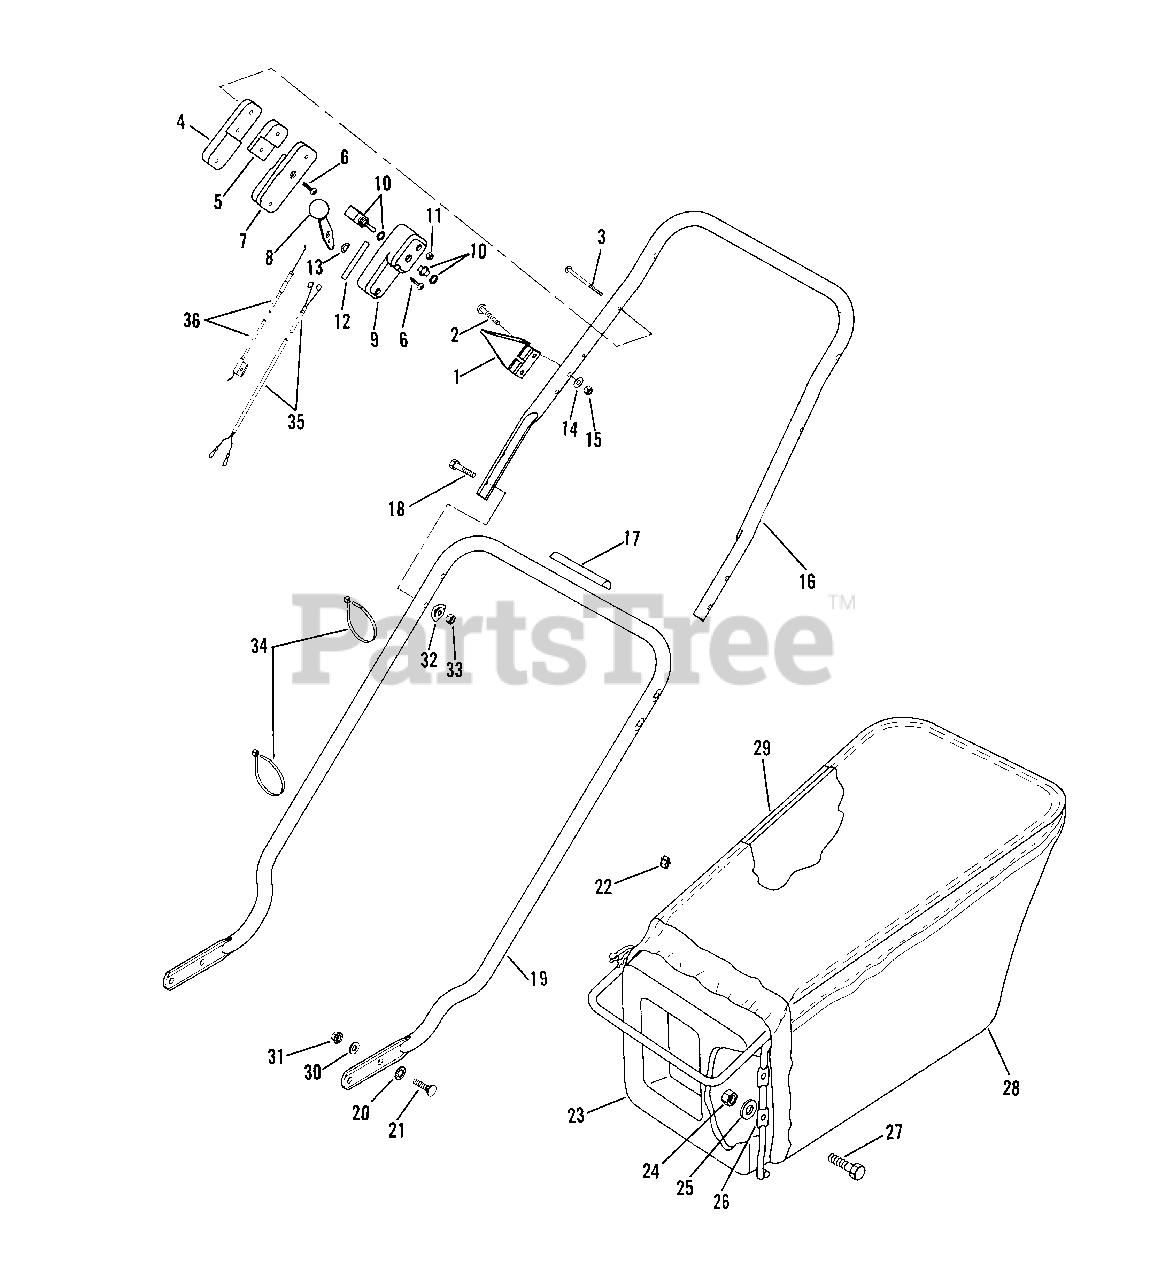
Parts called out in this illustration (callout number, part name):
1	Rope Guide Assembly
2	Screw-Rope Guide
3	Screw-Case to Handle
4	Control Case-Outer
5	Escutcheon Plate
6	Screw
7	Throttle Case-Center
8	Lever and Knob Assembly
9	Throttle Case-Inner
10	Switch Assembly
11	Nut
12	Decal-ON-OFF
13	Washer
14	Nut-Rope Guide
15	Washer
16	Handle-Upper
17	Decal-Special Training
18	Screw
19	Handle-Lower
20	Lockwasher
21	Bolt-Carriage
22	"S" Clip
23	Adapter
24	Nut
25	Washer
26	Latch Bar Assembly
27	Screw
28	Grass Bag
29	Hanger-Bag
30	Washer
31	Nut-Flanged
32	Washer-Curved
33	Nut
34	Tie Strap
35	Wire Harness Assembly
36	Throttle Cable
